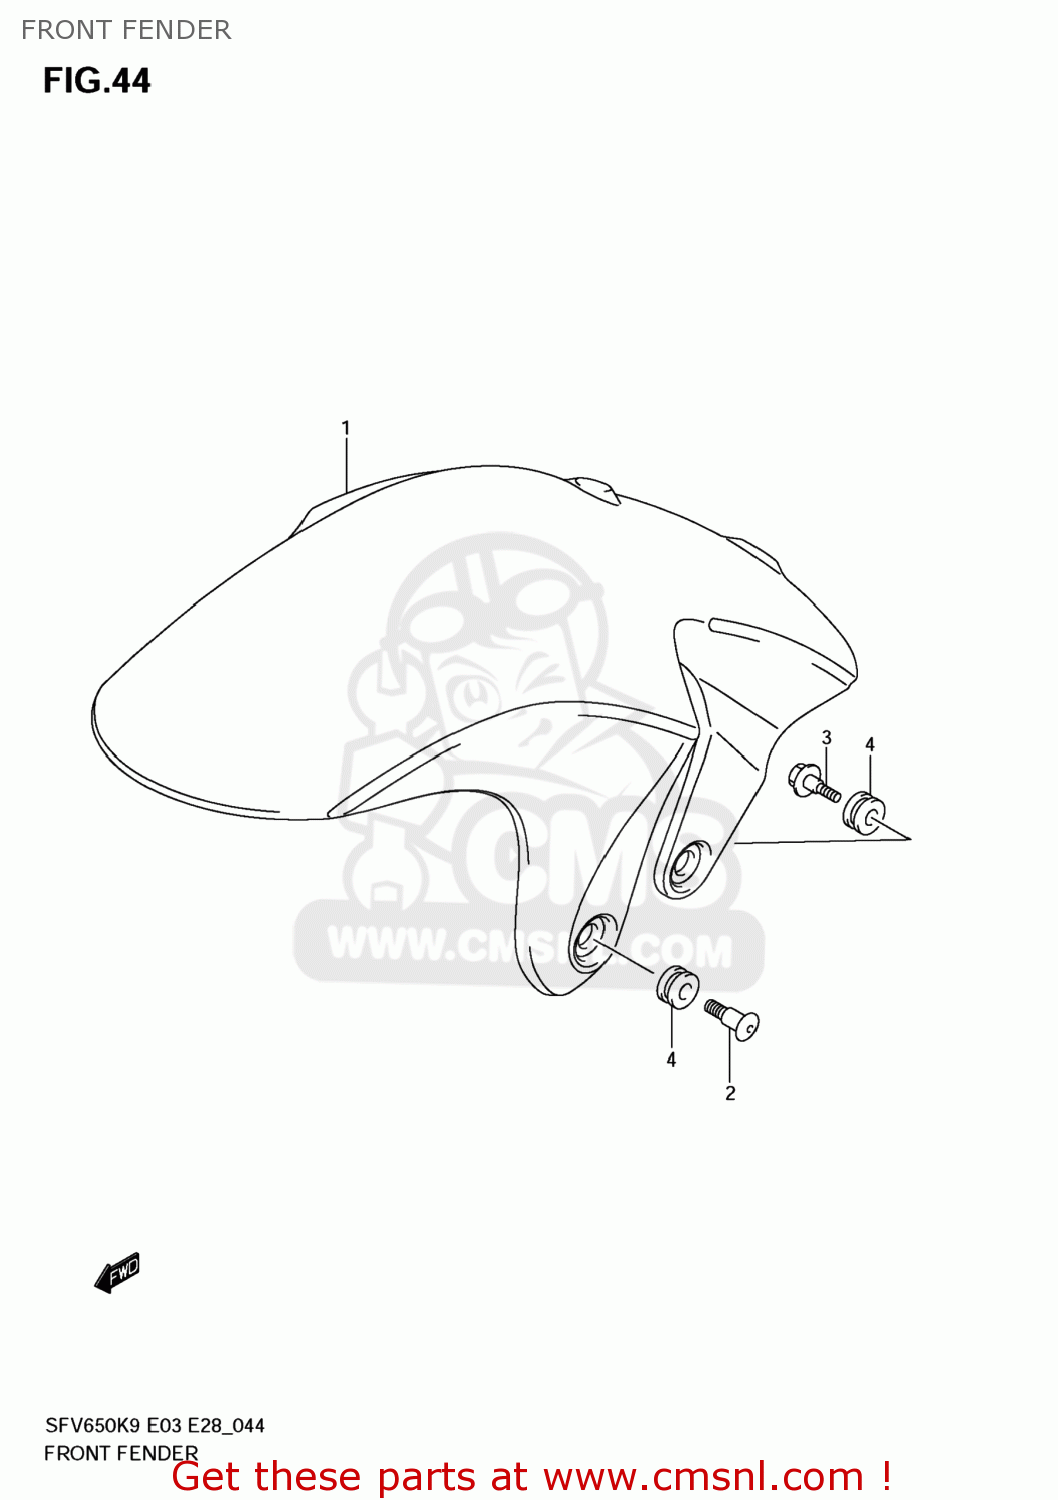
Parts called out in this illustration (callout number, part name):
1	FENDER,FR
2	SCREW(6X16)
3	BOLT(6X19)
4	CUSHION
